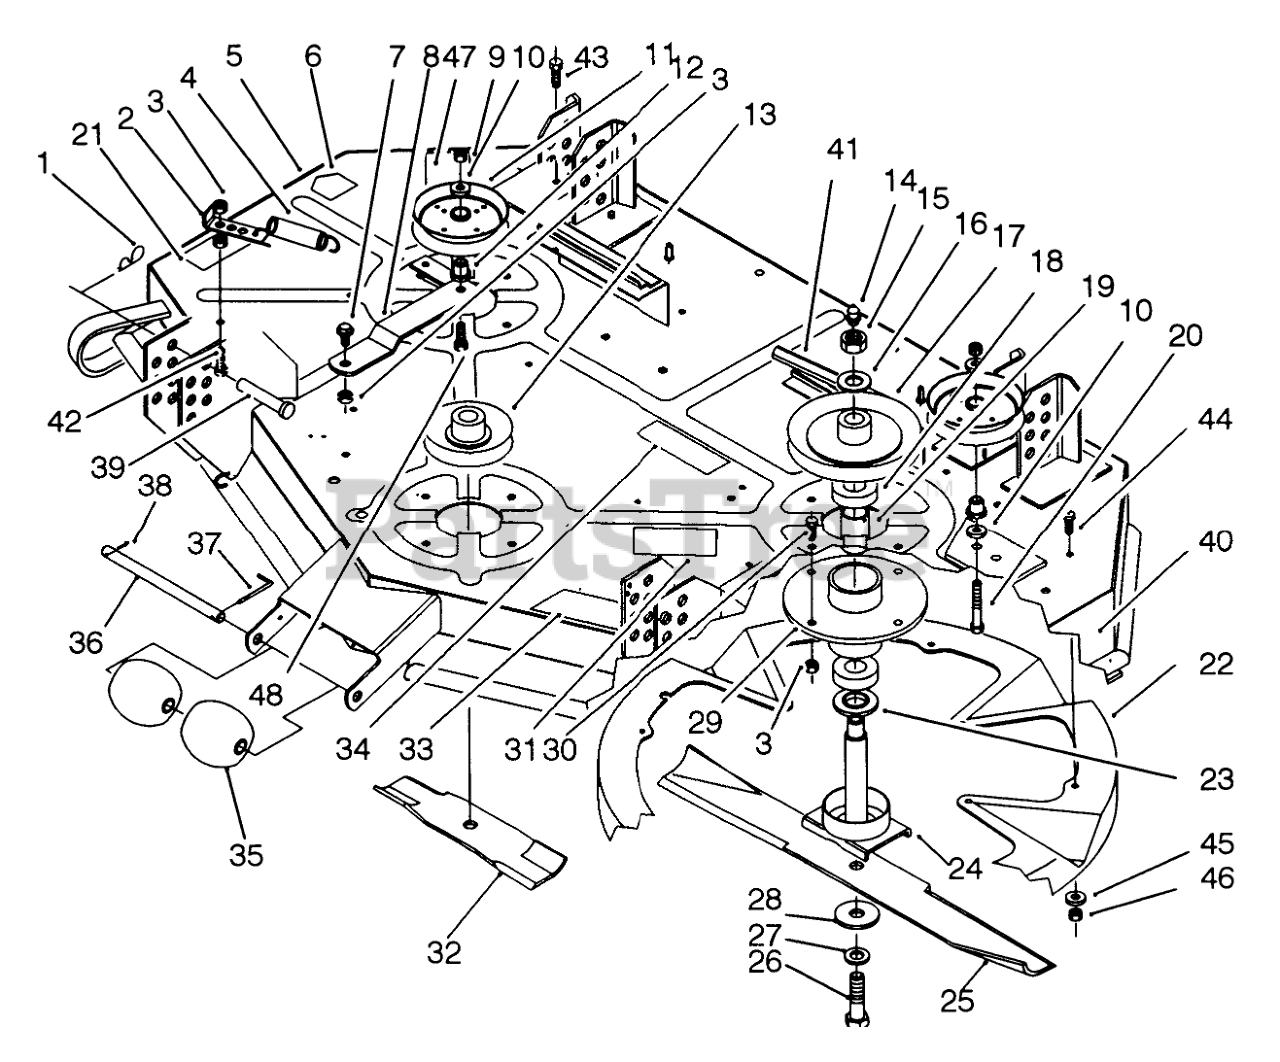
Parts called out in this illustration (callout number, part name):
1	PIN-HAIR
2	ANCHOR SPRING R
3	NUT-LOCK, NI
4	SPRING-EXTENSION, DECK
5	Deck-48" (Incl. Ref. # 6, 21, 31, 33, 34, 40, & 47)
6	DECAL-DANGER
7	SCREW-SHOULDER
8	IDLER LEVER WA R
9	NUT-LOCK, NI
10	WASHER-FLAT
11	PULLEY-IDLER
12	BUSHING-PULLEY
13	CENTER PULLEY
14	FITTING-GREASE
15	NUT-HEX
16	WASHER
17	PULLEY-DECK
18	BEARING-BALL
19	SPACER-BEARING
20	SCREW-HH
21	DECAL - DANGER
22	KICKER INSERT
23	SPACER-SPINDLE
24	SHAFT-SPINDLE
25	L/H BLADE
26	SCREW-BLADE
27	WASHER-LOCK
28	BLADE WASHER
29	HOUSING-SPINDLE
30	SCREW-HH
31	DECAL-DANGER
32	CENTER BLADE
33	DECAL-TORQUE
34	DECAL - BELT ROUTING
35	ROLLER
36	SHAFT-ROLLER
37	PIN-SPECIAL
38	PIN-COTTER
39	PIN-CLEVIS
40	DECAL - 48" RECYCLER
41	V-BELT (72)
42	SCREW-HH
43	SCREW-HH
44	SCREW-HH
45	WASHER-FLAT
46	NUT-LOCK, NI
47	DECAL - WARNING
48	SCREW-HH
